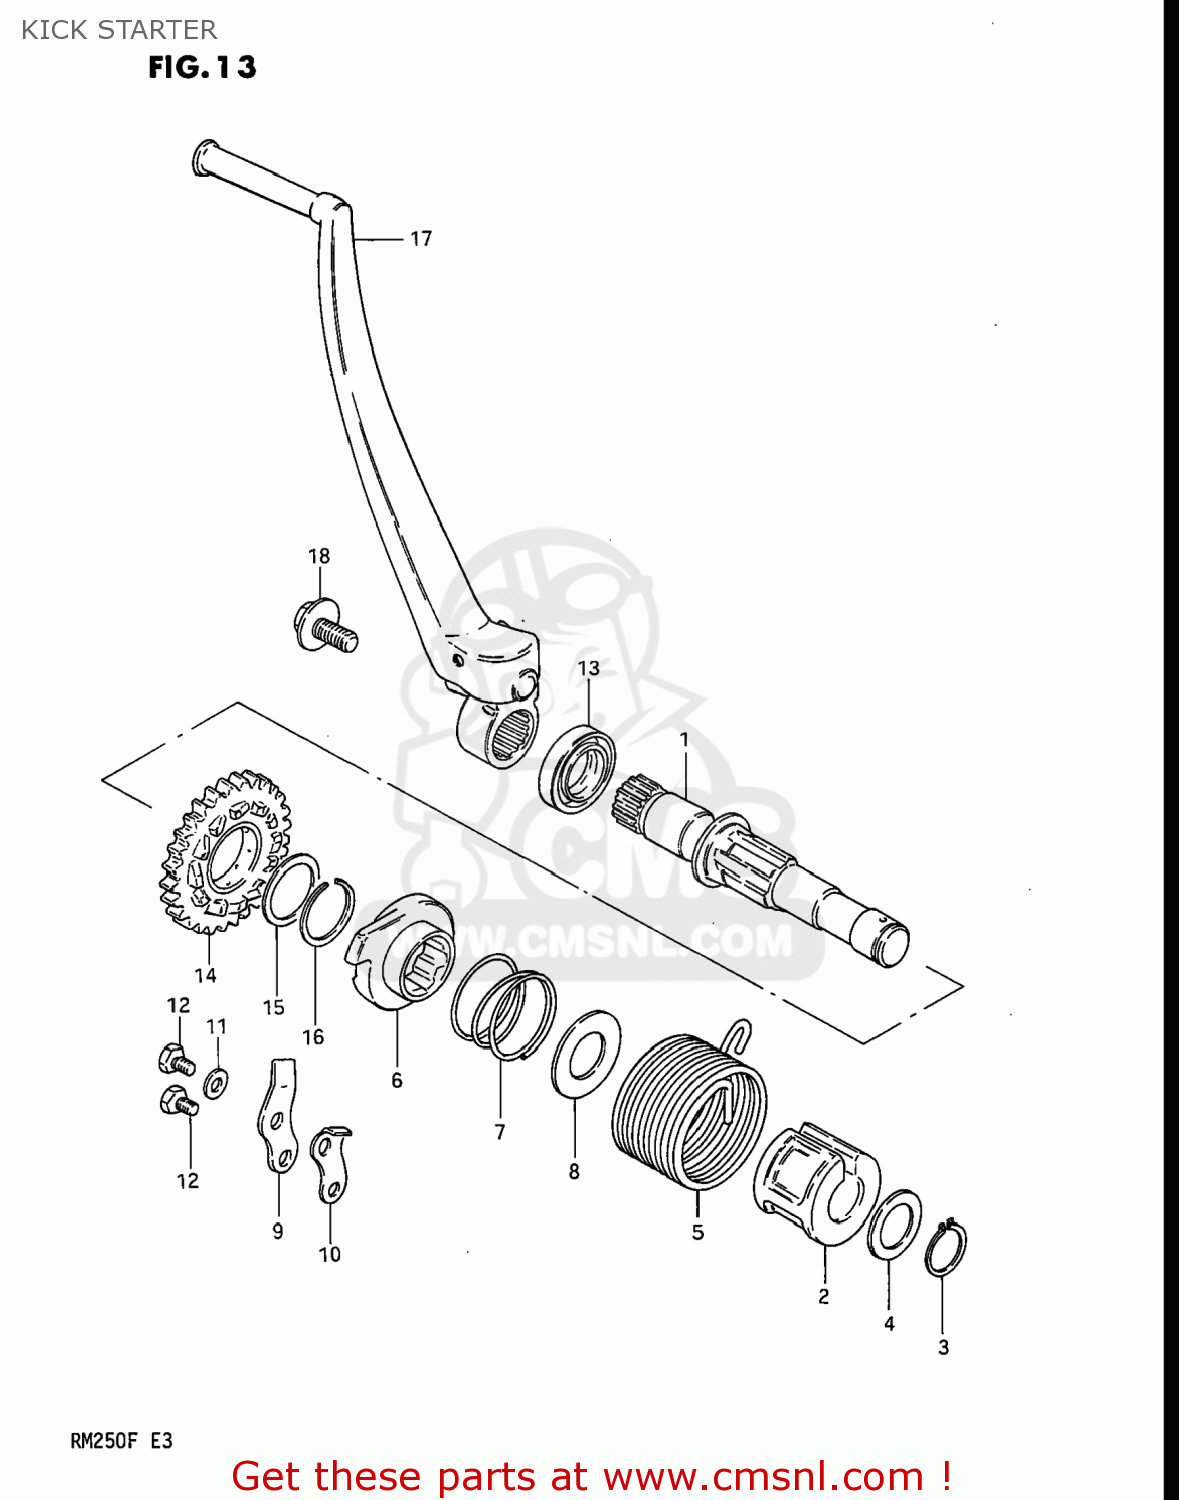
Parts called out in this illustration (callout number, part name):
1	SHAFT,KICK STARTER
2	GUIDE,KICK STARTER SFT SPRING
3	CIRCLIP
4	WASHER
5	SPRING
6	STARTER,KICK
7	SPRING
8	WASHER
9	GUIDE,KICK STARTER
10	STOPPER,KICK STARTER
11	WASHER
12	BOLT
13	SEAL,OIL(20X27X5)
14	GEAR
15	SHIM
16	CIRCLIP
17	LEVER ASSEMBLY,KICK STARTER
18	BOLT(8X14)
